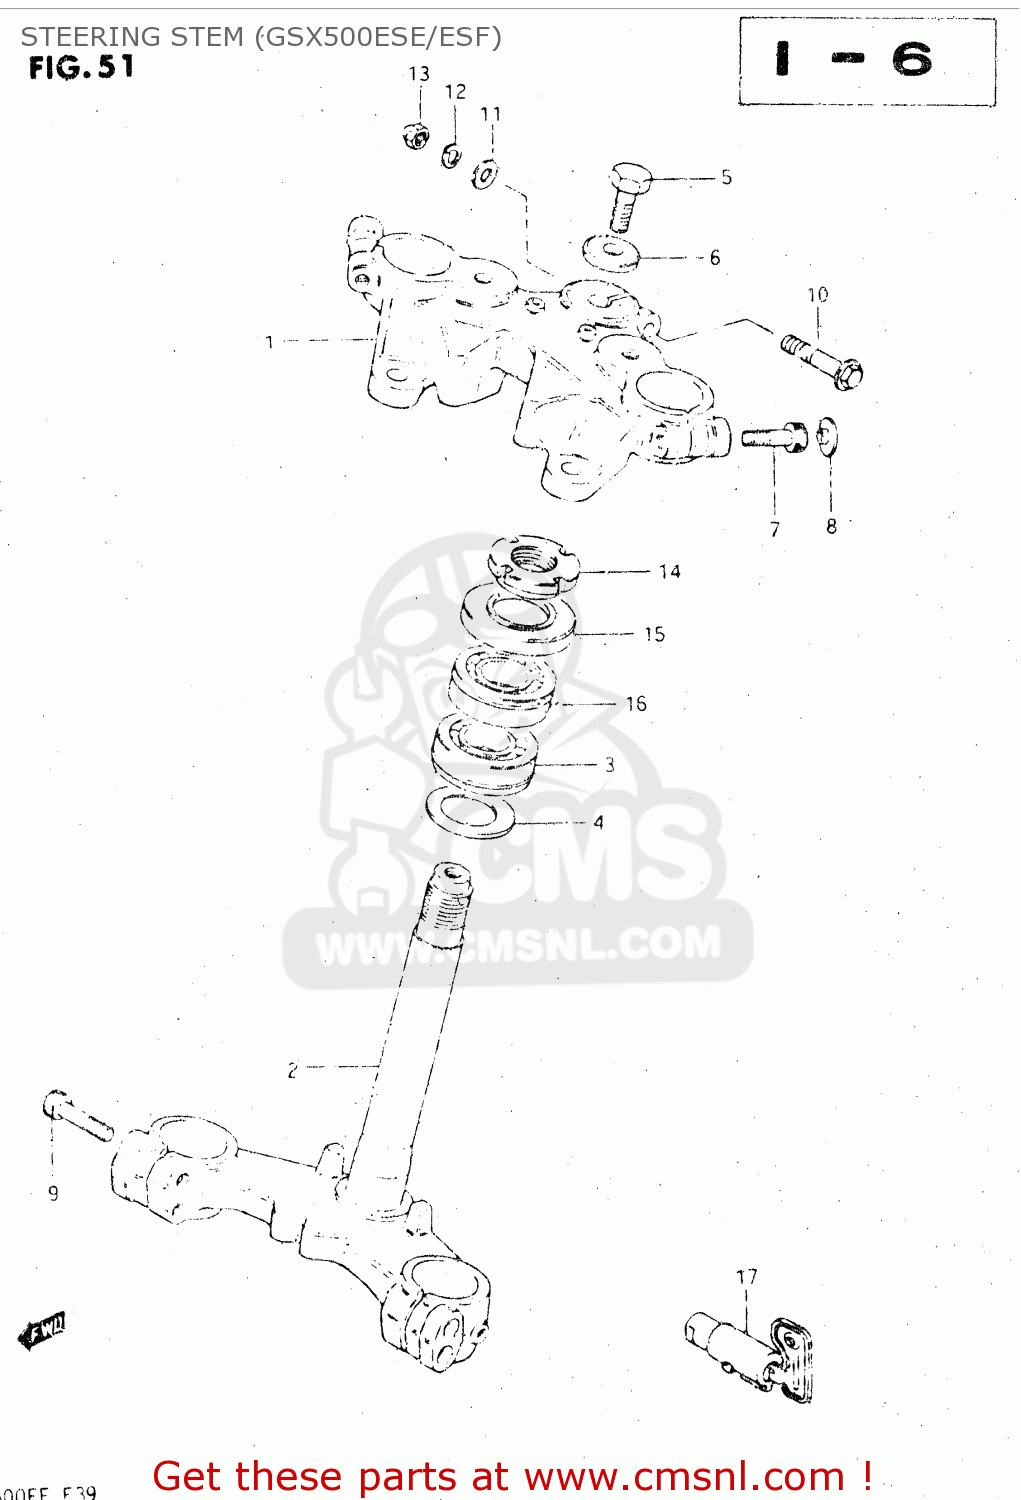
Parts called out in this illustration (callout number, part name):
1	HEAD,STEERING STEM
2	STEM,STEERING
3	BEARING
4	WASHER,THRUST
5	NUT,STEM HEAD
6	WASHER,STEERING STEM B
7	BOLT
8	CAP(OD:20)
9	BOLT, REAR (8X30)
10	BOLT, UPPER
11	WASHER,8.5X16X
12	LOCK WASHER
13	NUT,M8X1.25X12
14	NUT,STEERING STEM
15	DUST SEAL,STEERING UPR
16	TAPER,ROLLER BEARING
17	LOCK ASSY,STEERING(NEIMAN)
